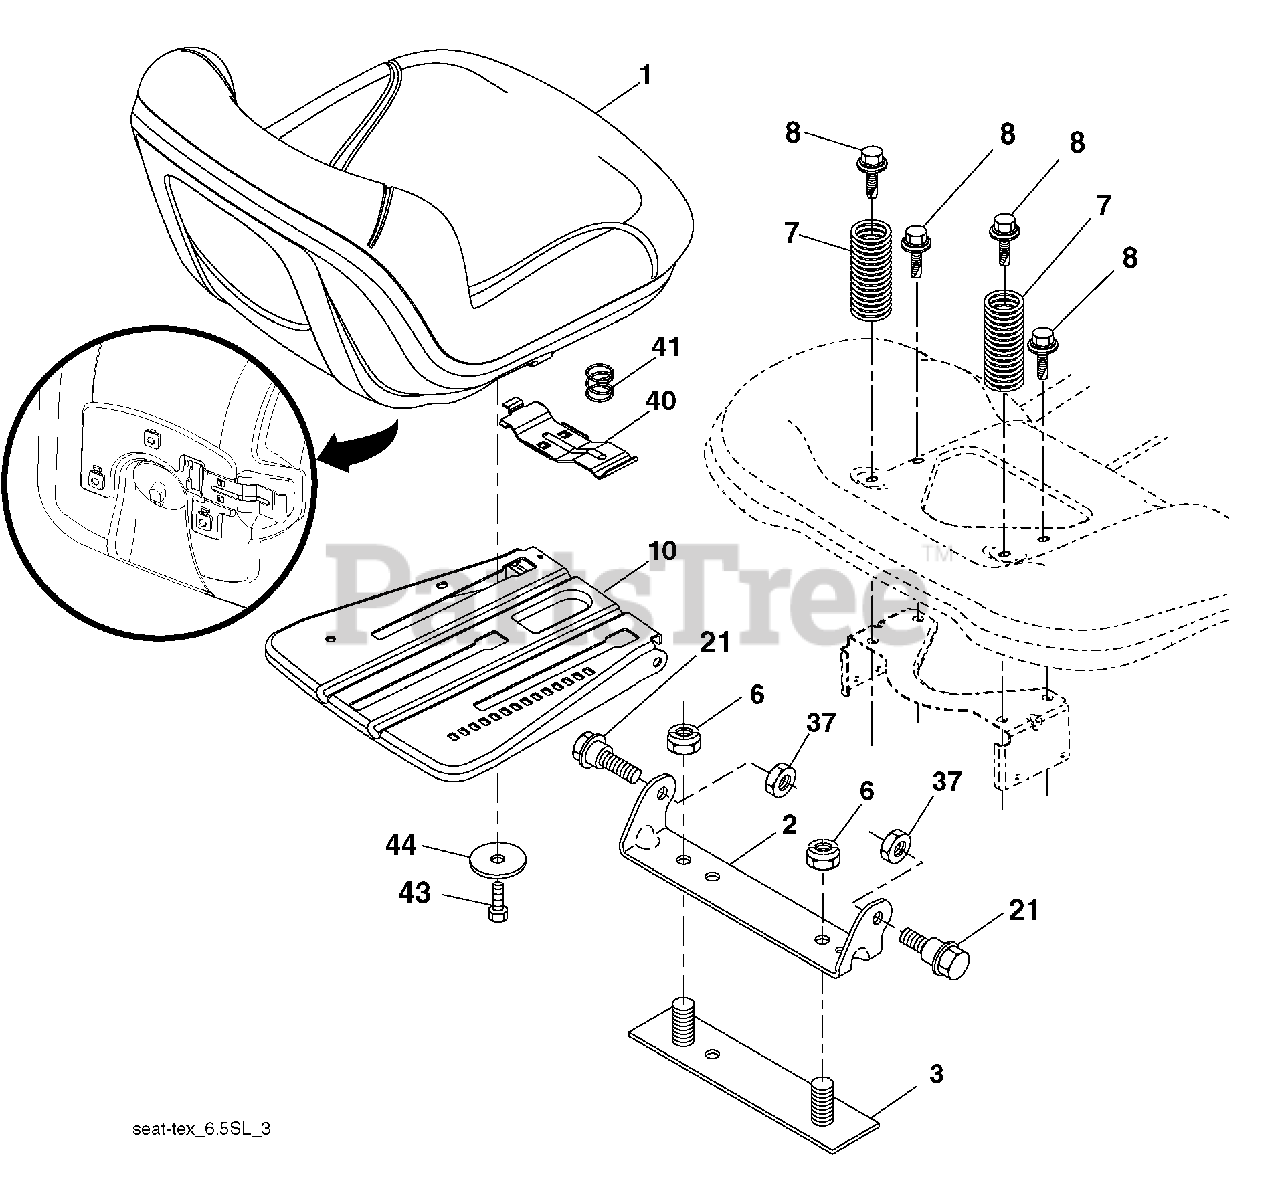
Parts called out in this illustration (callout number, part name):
1	Seat
2	Bracket Pivot Fender
3	Strap, Asm. Fender
6	Nut, Lock w/Ins. 3/8-16 unc
7	Spring, Seat Cprsn.
8	Bolt 5/16-18 unc x 3/4 w/Sems.
10	Pan, Seat
21	Bolt, Shoulder 5/16-18
37	Nut, Lock 5/16-18 unc
40	Handle Slide
41	Spring Latch
43	Bolt 3/8-16 unc x 3/4
44	Washer 13/32 x 2 3/8 x 12 Ga.
